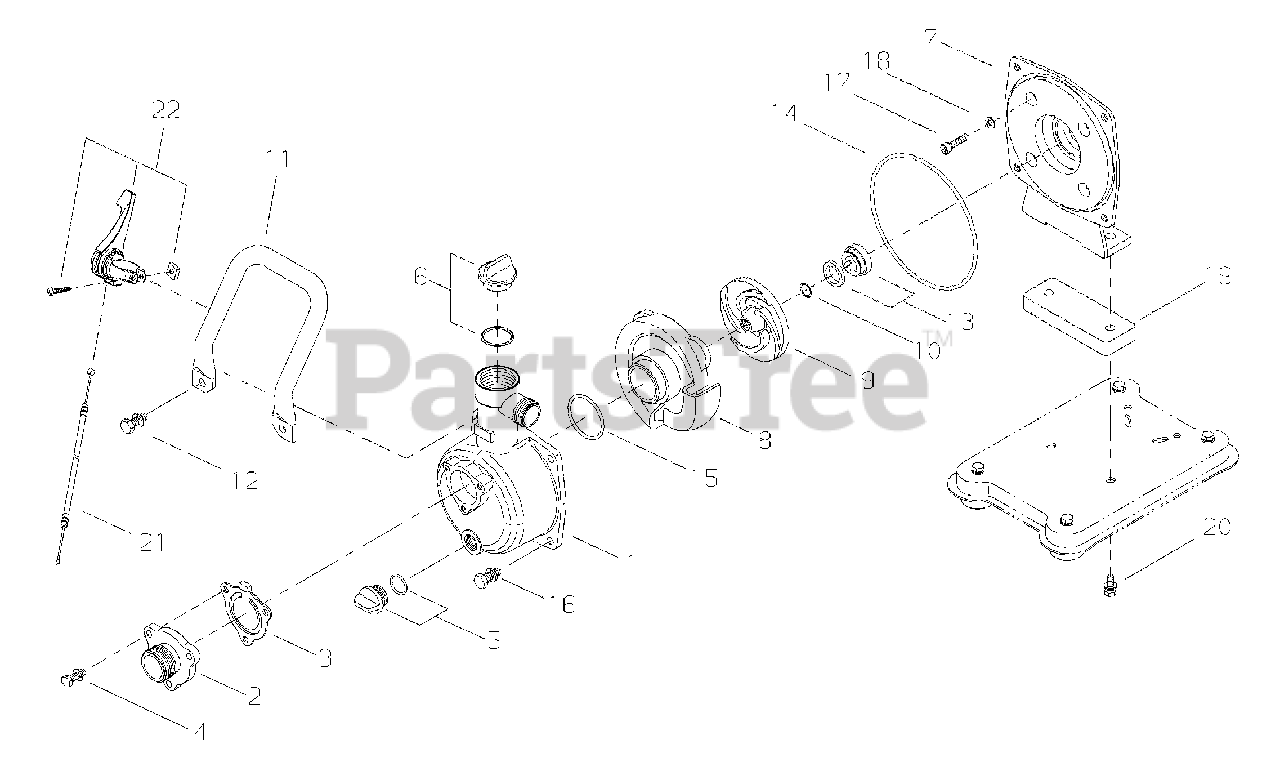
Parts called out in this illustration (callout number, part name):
1	CASE, PUMP
2	PORT, SUCTION
3	GASKET, PORT
4	BOLT M6×20
5	PLUG ASSY, DRAIN
6	PLUG ASSY, FILLER
7	COVER, PUMP
8	VOLUTE
9	IMPELLER
10	SHIM 0.3 MM THICK
11	HANDLE
12	BOLT M8×22
13	SEAL, MECHANICAL
14	O-RING, PUMP HOUSING
15	O-RING, FAN
16	BOLT M8×20
17	BOLT M6×55
18	WASHER, SEALING Ø6
19	SPACER 9 MM THICK
20	BOLT M8×25
21	CABLE, THROTTLE
22	THROTTLE CONTROL ASSY
